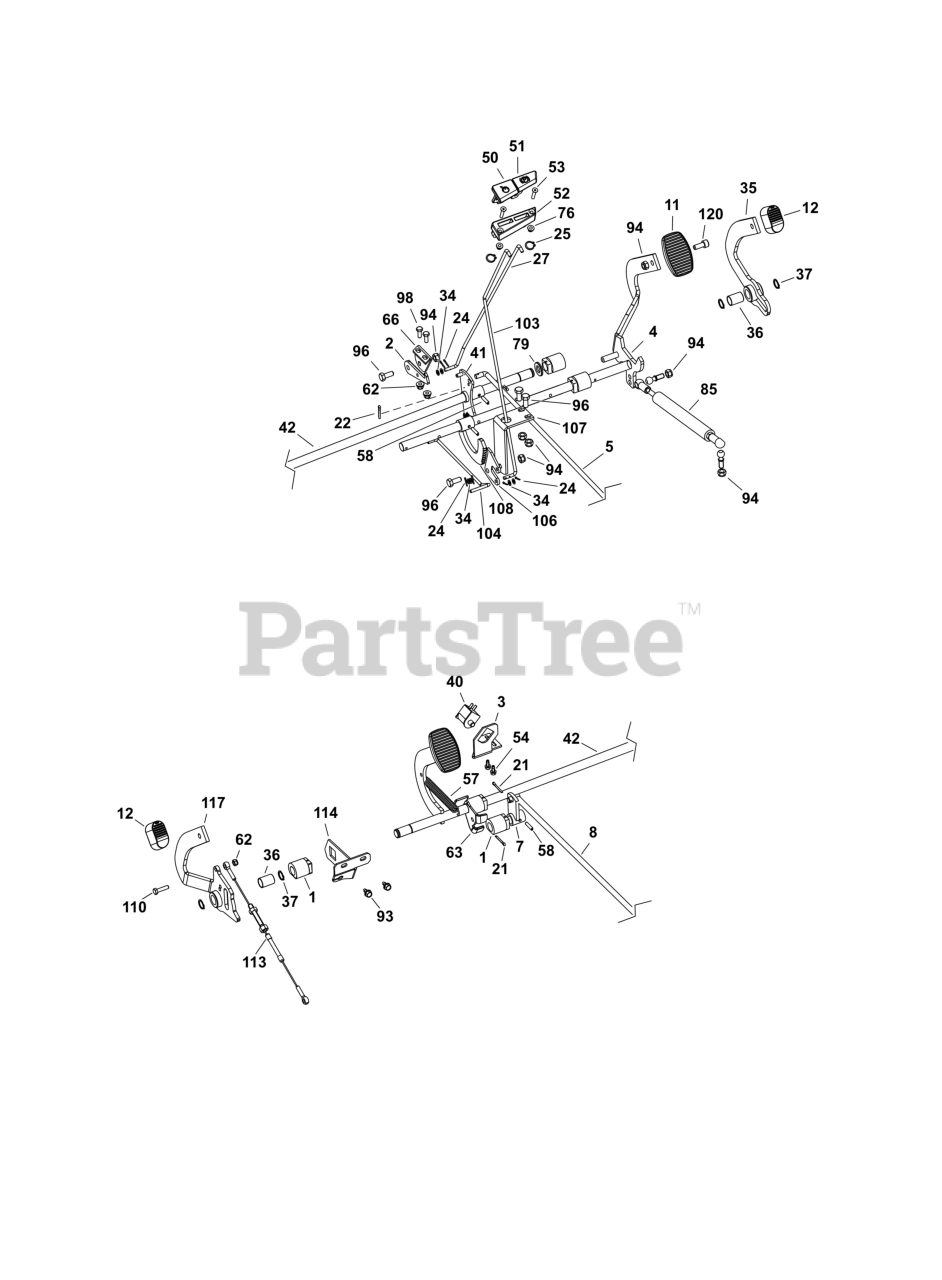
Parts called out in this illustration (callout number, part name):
3	BRACKET, Switch
5	ROD, Brake
11	PAD, Rubber
12	PAD, Foot
35	PEDAL, Foot
42	SHAFT, Brake
85	DAMPENER
113	CABLE, Differential Lock
117	PEDAL, Foot
